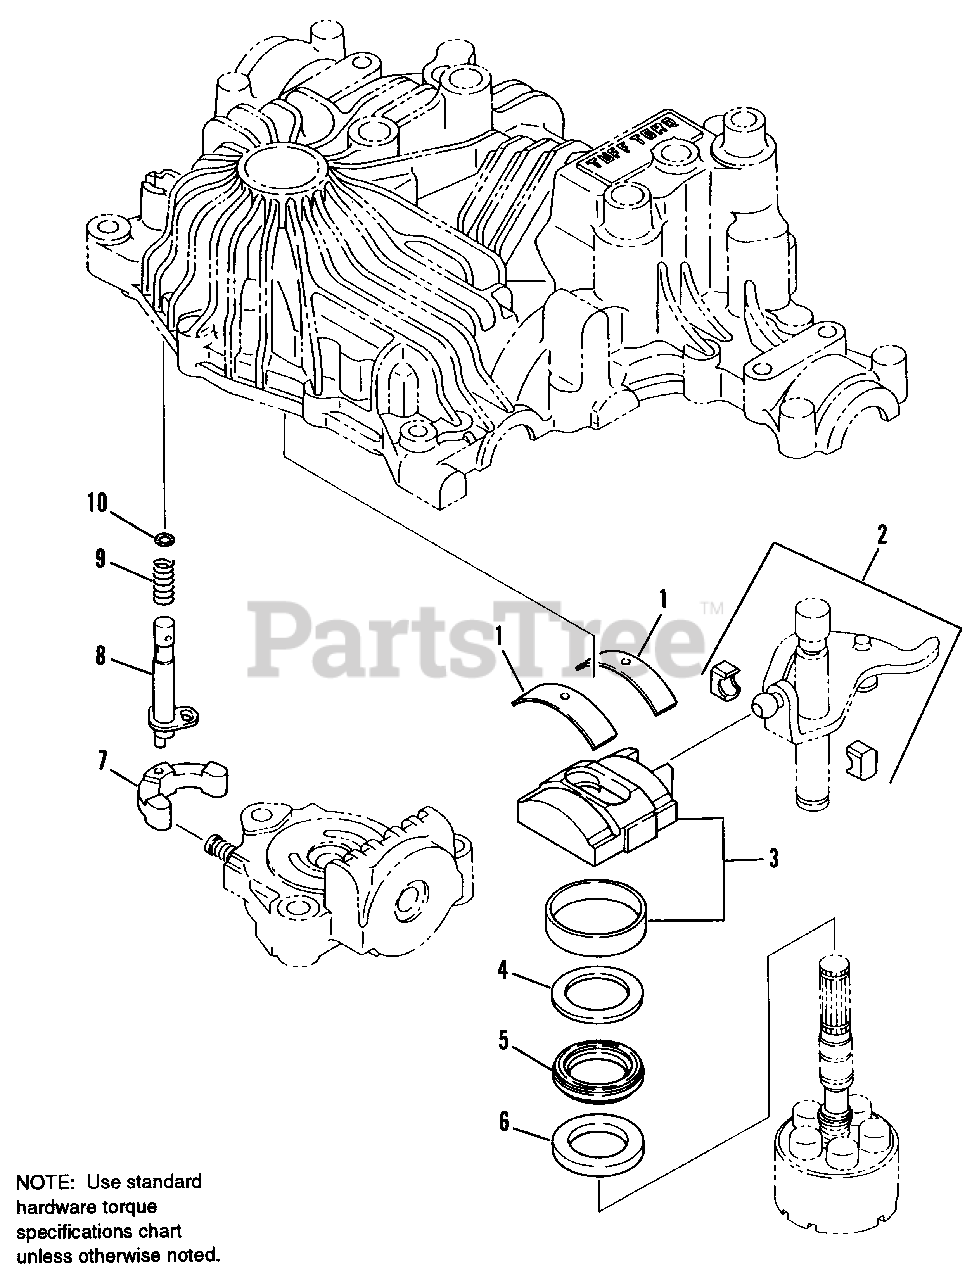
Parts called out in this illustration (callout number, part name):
1	THRUST BEARING
3	SWASH PLATE
4	THRUST PLATE
5	THRUST BEARING
6	THRUST PLATE
8	SHAFT, By-Pass
